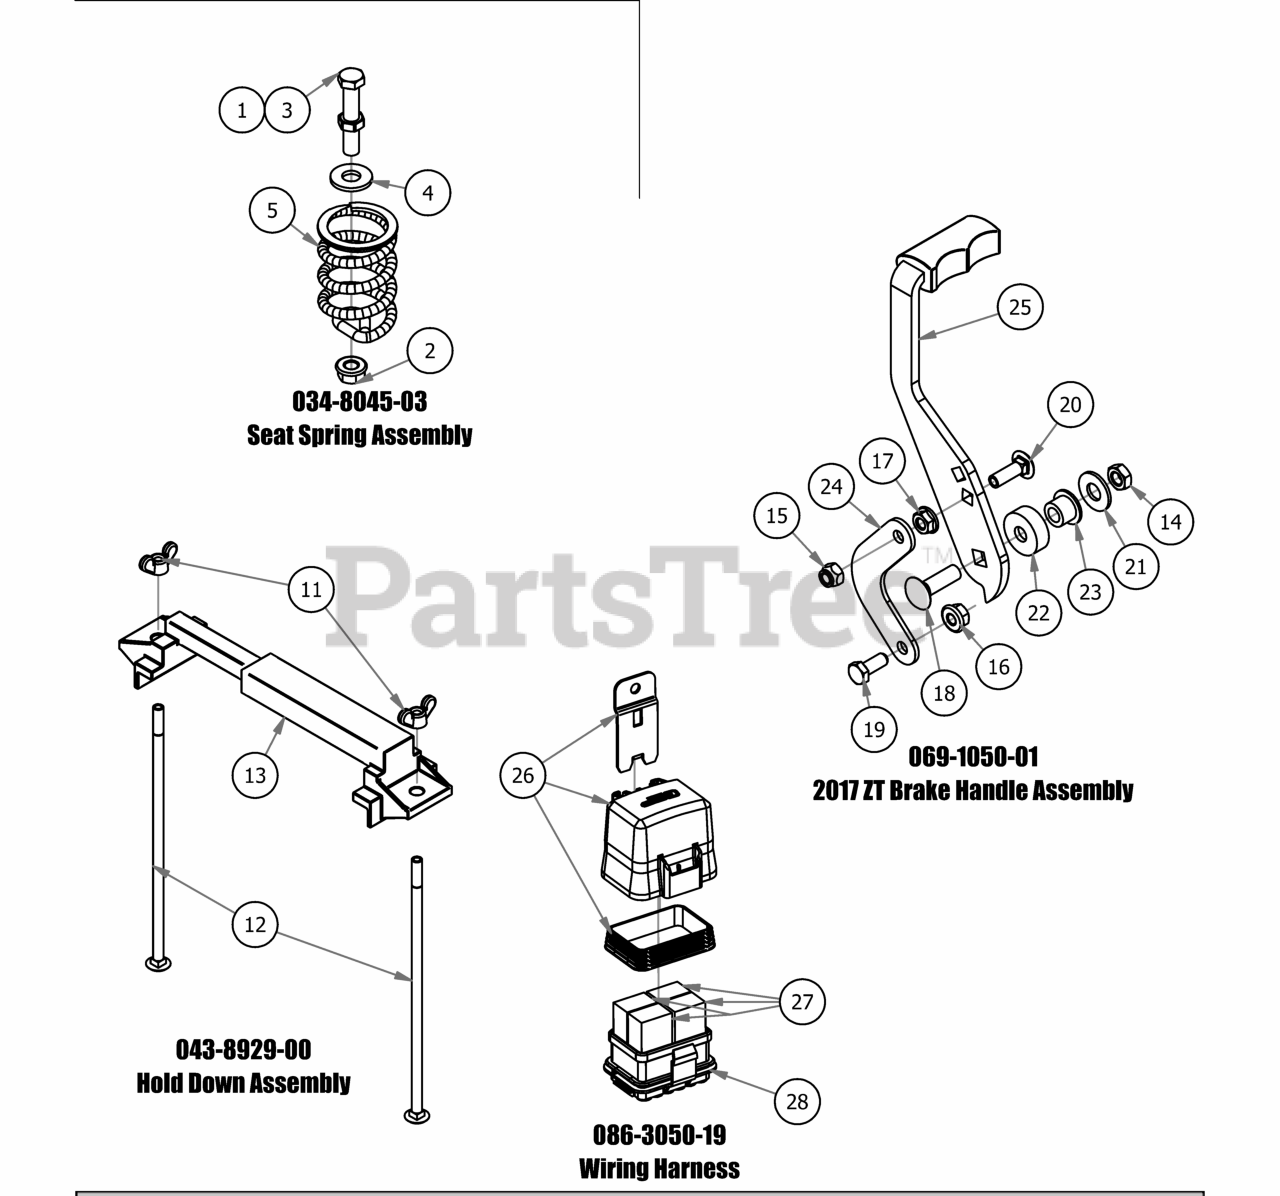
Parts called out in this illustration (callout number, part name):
1	3/8-16 Half Jam Nut
2	3/8" Flange Nut
3	3/8"-16 x 2" Gr 5 Hex Bolt
4	3/8" Flat Washer
5	Seat Spring
11	1/4" Wing Nut
12	1/4-20 X 8 Carriage Bolt
13	Battery Hold Down
14	3/8-16 HEX JAM 2-WAY REVERSIBLE CENTER LOCKNUT ZINC
15	5/16-18 NYLON INSERT CAP LOCKNUT ZINC (BLK CAP)
16	5/16-18 NYLON INSERT FLANGE LOCKNUT ZINC
17	5/16-18 HEX SERRATED FLANGE NUT HARD/ZINC
18	3/8-16 X 1-1/4 CARRIAGE BOLT ZINC
19	5/16-18 X 3/4 HEX CAP SCREW (GR.5) ZINC
20	5/16-18 X 1 CARRIAGE BOLT (GR.8) ZINC
21	3/8 FLAT WASHER USS (1" OD) ZINC
22	2015 Brake Lever Spacer
23	.377 ID X .625 OD X .500 HGT X .880 FLNG DIA X .060 FLNG THK
24	Brake Cable Adapter Bracket
25	Brake Handle
26	Relay Block Cover Replacement Kit
28	Wiring Harness (Includes Cover Replacement Kit and Relays)
